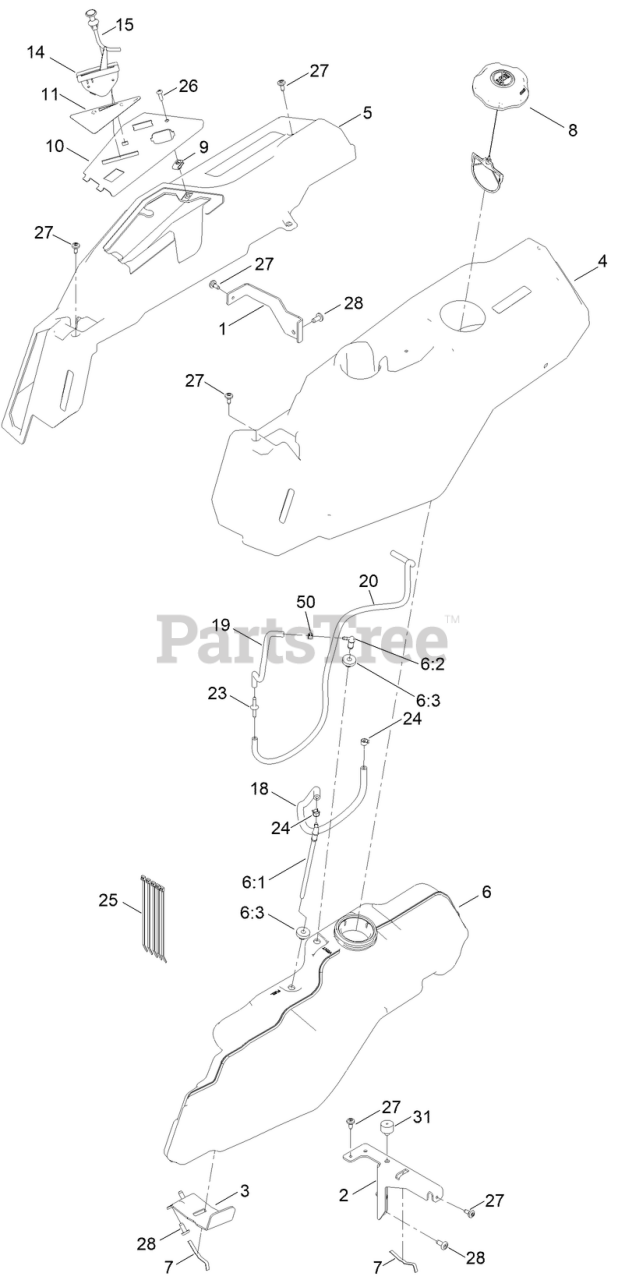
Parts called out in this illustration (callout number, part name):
1	BRACKET-POD
2	SUPPORT-POD, LH
3	SUPPORT-TANK, FUEL
4	POD-LH
5	POD-RH, MYRIDE
6	TANK-FUEL ASM
6:1	CONNECTOR-ELBOW, 90 DEG
6:2	FITTING-ELBOW 90
6:3	BUSHING
7	SPRING
8	CAP-FUEL, RATCHETING
10	PANEL - CONTROL
11	DECAL-PANEL, CONTROL
14	CABLE-THROTTLE
15	CABLE-CHOKE
18	HOSE-FUEL
19	HOSE-FUEL
23	ADAPTER ORIFICE
24	CLAMP-HOSE
25	TIE-CABLE
26	SCREW-PRH
27	SCREW-SHOULDER
31	BUMPER-GROMMET
50	CLAMP-HOSE
